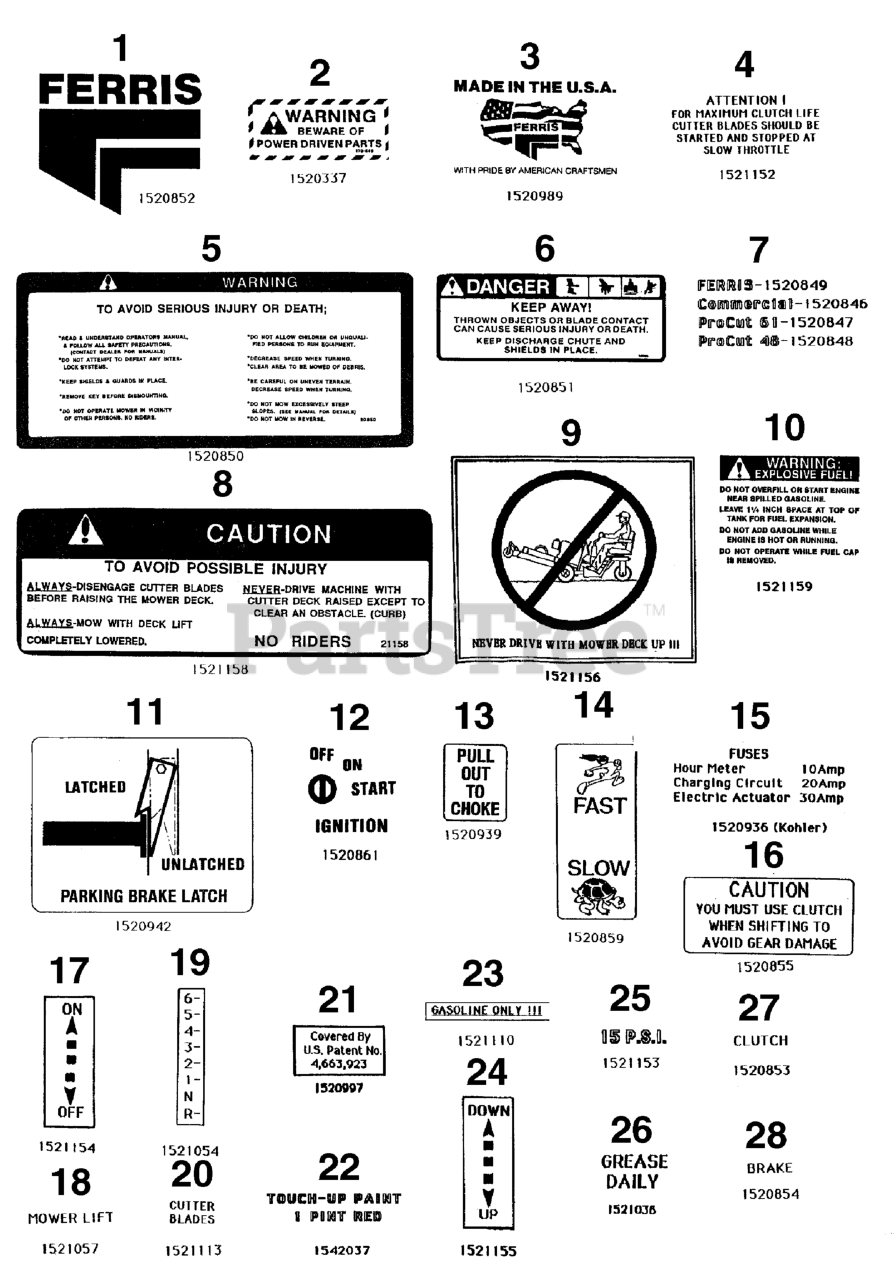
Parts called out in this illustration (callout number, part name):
1	DECAL, Ferris Logo, 10-3/4"
2	DECAL, Warning
3	DECAL, Made In The USA
4	DECAL, Attention Belt Life
5	DECAL, WARNING Operation
6	DECAL, DANGER DO NOT OPERATE W/O DEFLECT
7	DECAL, FERRIS TEXT & LOGO
7	DECAL, Commercial
7	DECAL, Word, PROCUT 61
7	DECAL, Word, PROCUT 48
9	DECAL, Never Drive With Mower Deck Up
10	DECAL, EXPLOSIVE FUEL
11	DECAL, Parking Brake Latch
12	DECAL, Ignition
14	DECAL, Engine Speed
15	DECAL, Fuses
16	DECAL, CAUTION Gear Damage
17	DECAL, PTO Switch
18	DECAL, Mower Lift
19	DECAL, Shift Pattern
20	DECAL, PTO Switch
21	DECAL, Patent
22	DECAL, Touch-Up Paint
23	DECAL, Gasoline Only
24	DECAL, Up / Down
25	DECAL, 15 P.S.I.
26	DECAL, Grease Daily
27	DECAL, Clutch, Word
28	DECAL, Brake, Word
